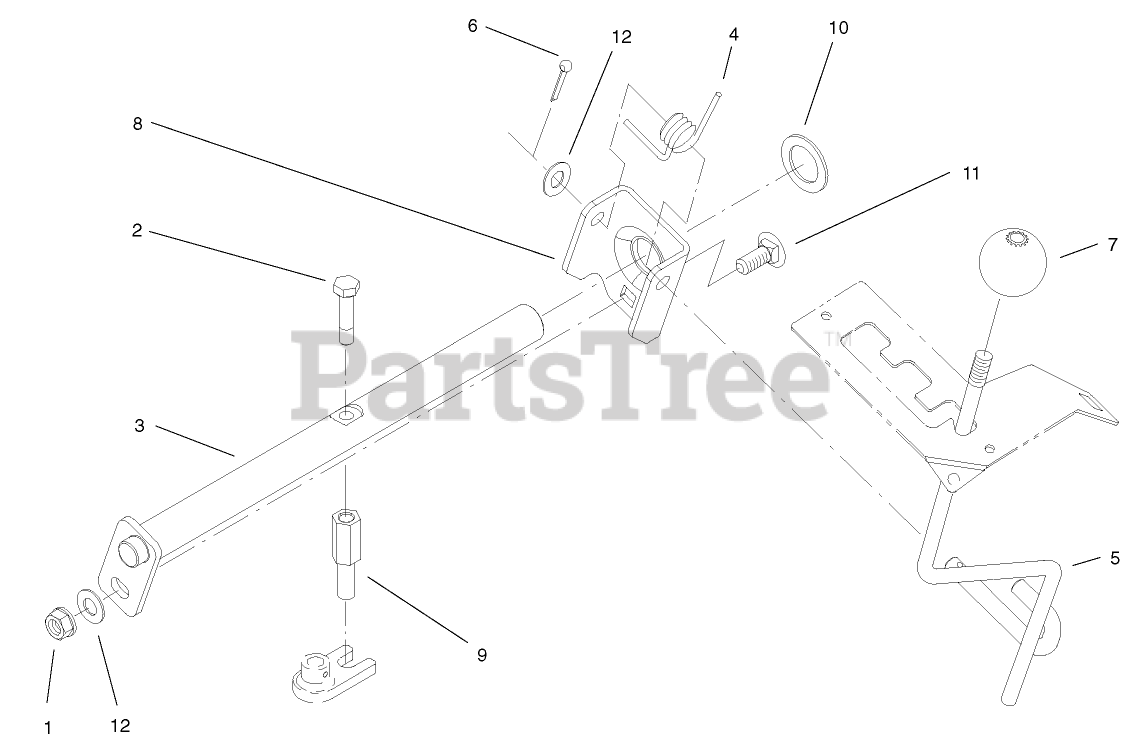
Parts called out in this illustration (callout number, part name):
1	NUT-LOCK, NI
2	SCREW-THREAD LOCKING
3	SHIFT ROD ASM
4	SPRING-TORSION
5	LEVER-SHIFT
6	PIN-COTTER
8	BRACKET-PIVOT
9	ROD-PIVOT, SHIFT
10	SPACER
11	SCREW-CARR
12	WASHER-FLAT
